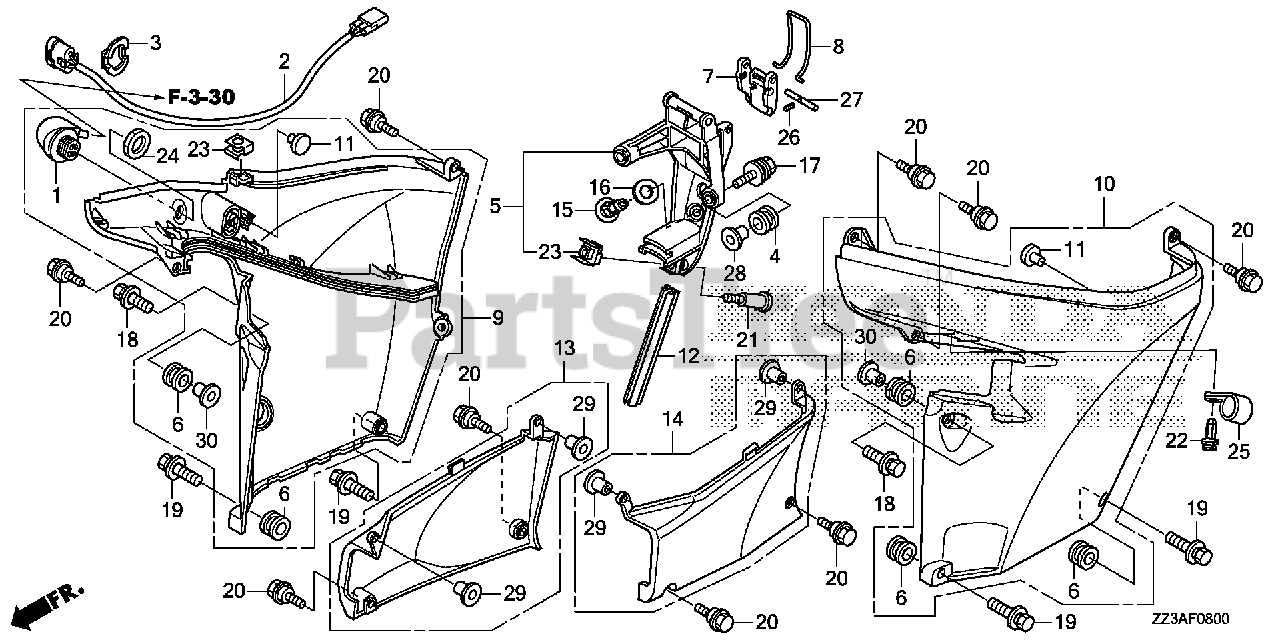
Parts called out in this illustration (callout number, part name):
1	CAP, WATER JOINT
2	SWITCH ASSY., POWER TILT
3	STAY, POWER TILT SWITCH
4	GROMMET, CASE (LOWER)
5	BRACKET, RR. COVER (LOWER)
6	RUBBER, FENDER MOUNTING
7	LEVER, FASTENER
8	WIRE, FASTENER
9	COVER ASSY., R. ENGINE (LOWER) *NHB14M* (AQUA MARINE SILVER METALLIC)
10	COVER ASSY., L. ENGINE (LOWER) *NHB14M* (AQUA MARINE SILVER METALLIC)
11	RUBBER, CUSHION
12	SEAL, RR. COVER (LOWER)
13	COVER, R. MOUNTING (LOWER) *NHB14M* (AQUA MARINE SILVER METALLIC)
14	COVER, L. MOUNTING (LOWER) *NHB14M* (AQUA MARINE SILVER METALLIC)
15	GROMMET, WATER CHECK
16	SEAL, WATER CHECK GROMMET
17	BOLT-WASHER (6X25)
18	BOLT-WASHER (6X22)
19	BOLT-WASHER (6X27)
20	BOLT, SPECIAL (6X17)
21	BOLT, RR. BRACKET
22	SCREW, RIVET (5X10)
24	NUT, HEX. (16MM)
25	CLIP (10.7MM)
26	PIN, SPRING (2.0X12)
27	PIN (5X59)
28	COLLAR, MODULE IGNITION CONTROL CASE (CDI)
29	COLLAR, DISTANCE (6.5X9X11.5)
30	COLLAR, DISTANCE (6.2X7.5)
